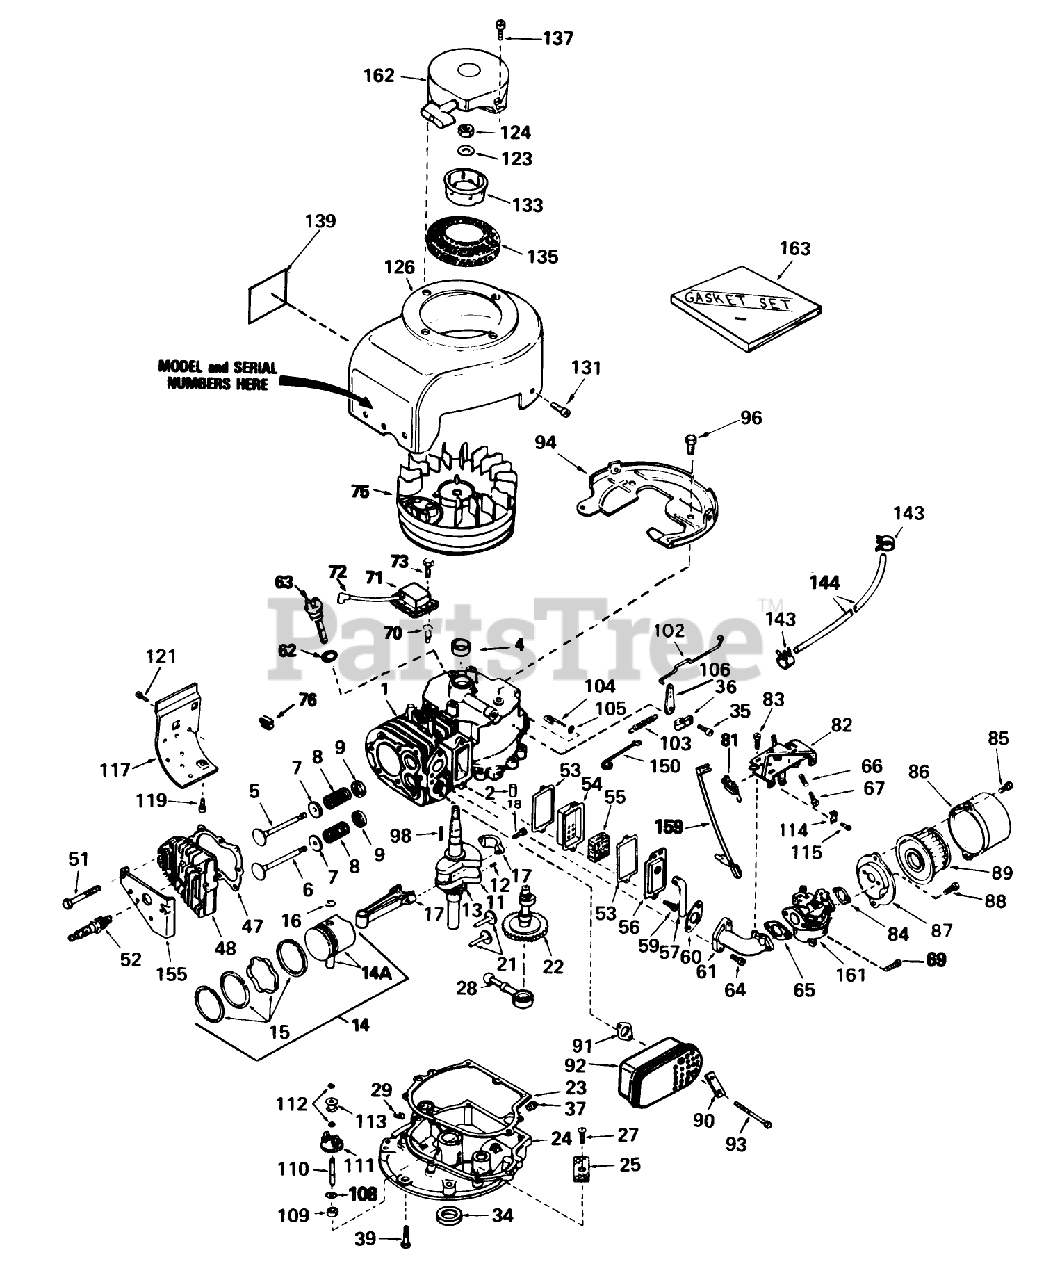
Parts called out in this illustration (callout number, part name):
1	Cylinder Assy. (Incl. Ref. #2 4)
2	Pin-Dowel
4	Oil Seal
5	Valve, Intake (Standard)(Incl. No. 9)
5	Valve, Intake (1/32" oversize)(Incl. No. 9)
6	Valve, Exhaust (Standard)(Incl. No. 9)
6	Valve, Exhaust (1/32" oversize)(Incl. No. 9)
7	Cap-Spring, Valve
8	Spring-Valve
9	Keeper-Spring, Valve
11	Crankshaft Assy. (Incl. Ref. #12 13)
12	Pin, Groove
13	Gear-Crankshaft
14	Piston, Pin Ring Assy. (Std.)(Incl. Ref. #14A, 15 16)
14	Piston, Pin Ring Assy. (.010 Oversize)(Incl. Ref. #14A, 15 16)
14	Piston, Pin Ring Assy. (.020 Oversize)(Incl. Ref. #14A,15 16)
14A	Piston Pin Assy. (Std.)(Incl. Ref. #16)
14A	Piston Pin Assy. (.010 Oversize)(Incl. Ref. #16)
14A	Piston Pin Assy. (.020 Oversize)(Incl. Ref. #16)
15	Ring Set (Std.)
15	Ring Set (.020" OS)
15	Ring Set (.010" OS)
17	Rod Assy., Connecting (Incl. Ref. #18)
18	Bolt, Connecting Rod
21	Lifter-Valve
22	Camshaft (Mechanical Compression Release)
23	Gasket-Cover, Cylinder
24	Flange Assy., Mounting (Incl. #25, 27, 34, 37 110)
25	Screen-Oil Filter
27	Screw
28	Pump, Oil
29	Plug-Pipe (Internal Hex, 1/4-18)
34	Seal-Oil
35	Screw
36	Clamp-Lever, Governor
37	Plug-Drain, Oil (SQH 1/4-18)
39	Screw (1/4-20 x 1-1/4)
47	Gasket-Head, Cylinder
48	CYLINDER HEAD
51	Screw (5/16-18 X 2-1/2)
52	Plug, Spark (J17LM or equiv.)
52	Plug, Spark (Champion RCJ-8)
53	Gasket-Breather
54	Body-Breather
55	Element-Breather
56	Cover-Valve
57	Tube-Breather
59	Screw
60	Gasket-Intake
61	Pipe-Intake
62	Gasket
63	Dipstick, Oil (Incl. No. 45)
64	Screw (T-30, 5/16-18x1-3/32)
65	Gasket
66	Spring-Compression
67	Screw
69	Screw-Hex Hd.
71	Solid State
72	Cover-Spark Plug
73	Screw
75	FIywheel
76	Clip-Wire
81	Terminal
82	Control Assy.Speed (Incl. Ref. #79 80)
83	Screw (10-24 x 9/16)
84	Gasket
85	Screw
86	Body-Air Cleaner
87	Bracket
88	Screw (10-32 x 1/2)
89	Element
90	62513 SNWTHWR W/284
91	Gasket Exhaust
92	Muffler
93	Screw Hex Hd.
94	Baffle Blower Housing
96	Screw (1/4-20x19/32)
98	Key-Flywheel
102	Link Governor
103	Spring Governor
104	Rod, Governor (Incl. Nos. 146)
105	Washer-Flat
106	Lever-Governor
108	Washer-Flat
109	Spacer Assy. Governor (Incl. Ref. #41)
110	Shaft, Governor
111	Governor Gear ASM
112	Ring-Retaining
113	Spool-Governor
114	Conduit
115	Screw (10-32 x 3/8)
117	Extension-Blower Hsng.
119	Screw
121	Screw
123	Washer-Belleville
126	Housing Blower
131	Screw
133	Cup-Starter
135	Screen-Starter
137	Screw
139	Decal-Instruction
143	Clamp-Line, Fuel
144	Line-Fuel
150	Link Governor Spring
155	Cover-Head, Cylinder
159	Wire-Ground
161	Carburetor (Incl. Ref. #65)
162	tarter-Rewind
163	Gasket Set
